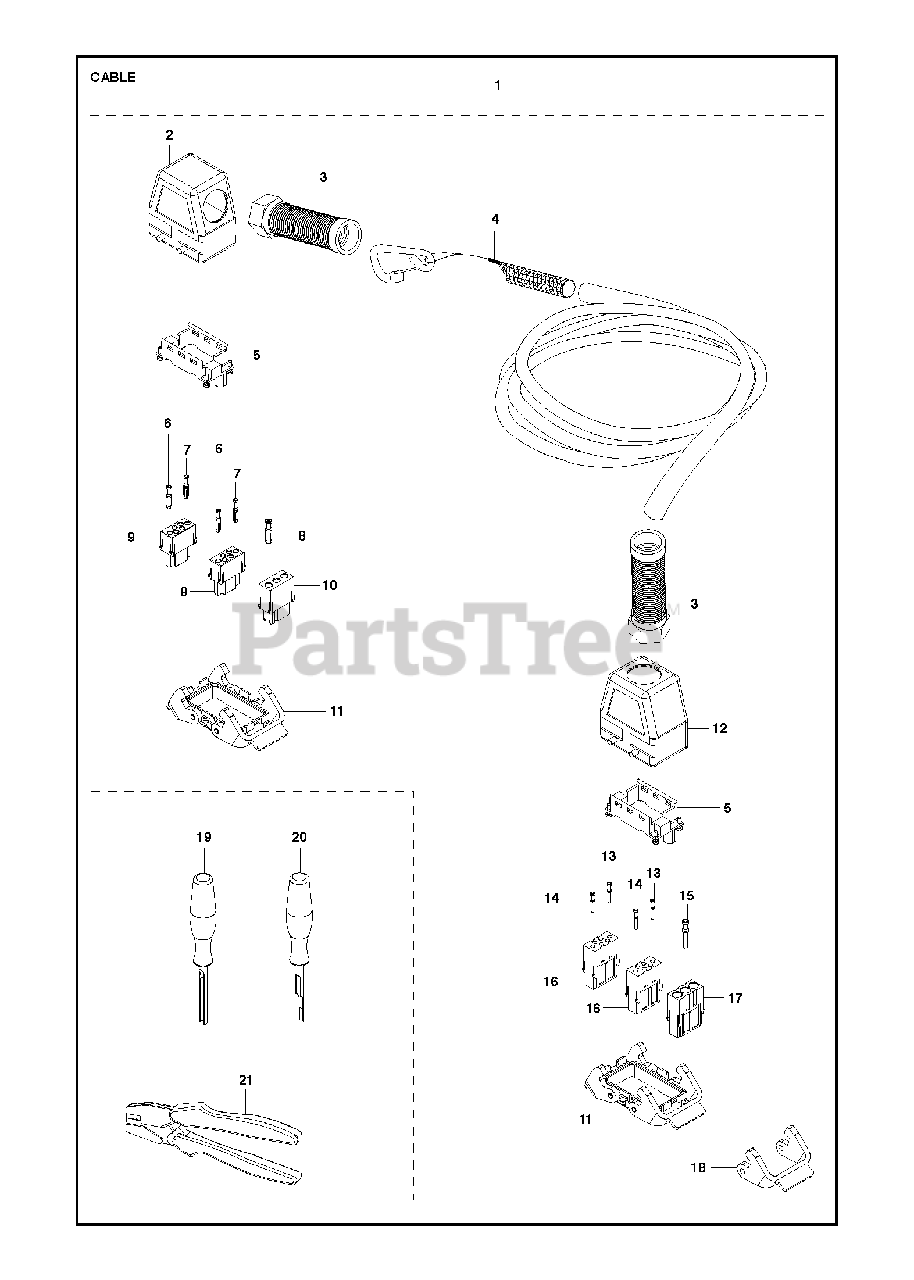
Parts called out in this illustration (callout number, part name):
6	TERMINALFemale 0,75mm²
7	TERMINALFemale 2,5mm²
14	TERMINALMale 0,75mm²
